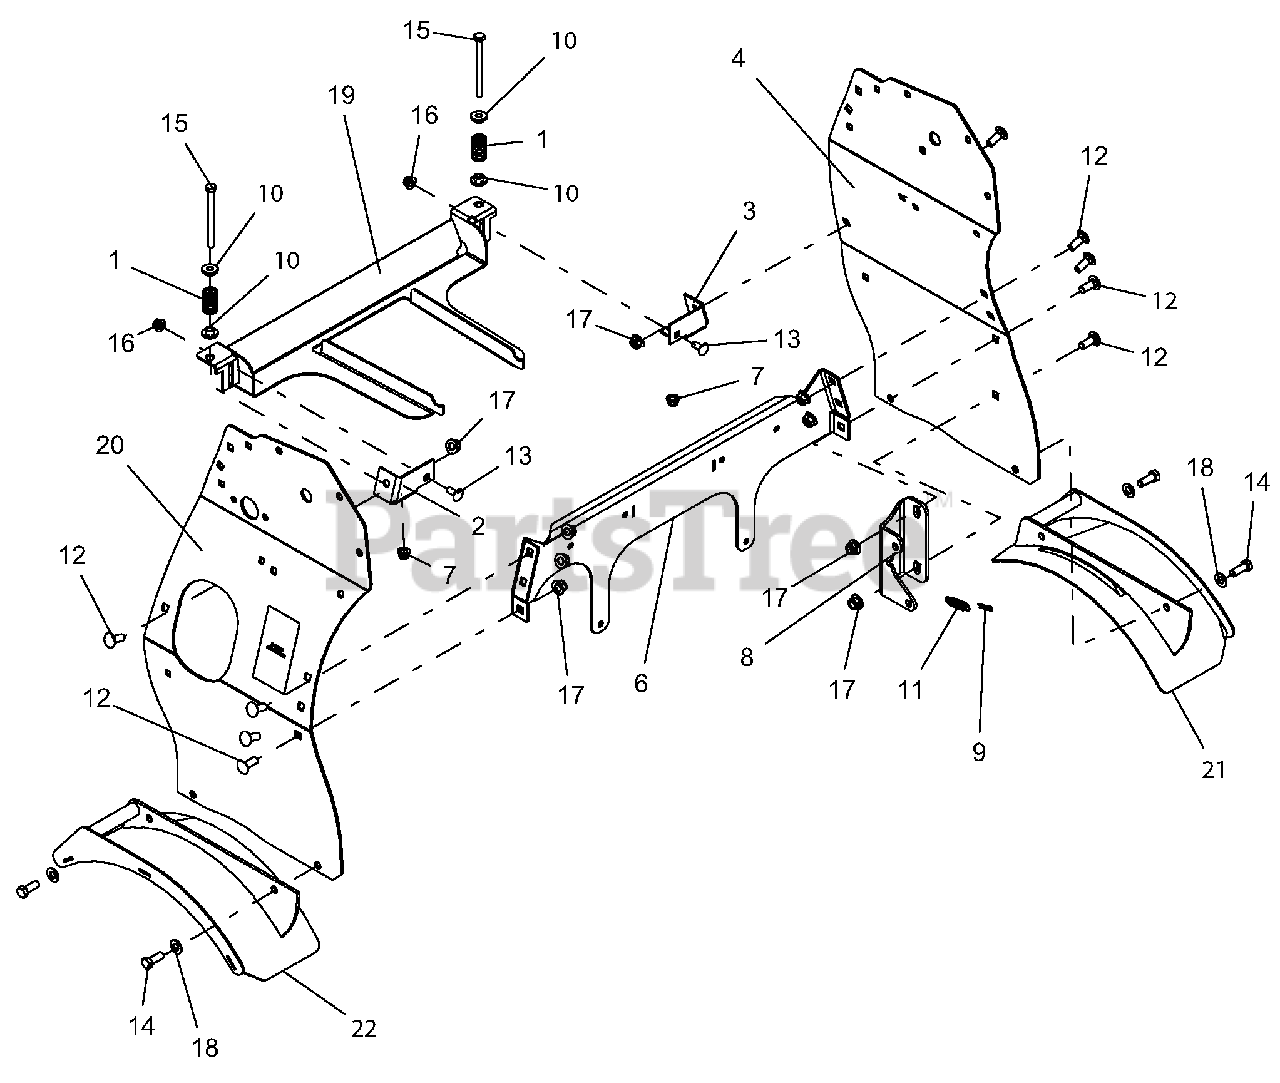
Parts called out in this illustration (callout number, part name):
1	SPRG, COMPRESSION
2	WLDMT, TANK HOLDDOWN-RH
3	WLDMT, TANK HOLDDOWN-LH
4	SIDE, LH PROSTANCE TOWER
6	BRKT, CONTROL TOWER STIFFENER
7	NUT-LK-NYL-FLG .31-18 YWZC
8	BRKT, TOWER SUPPORT
9	PIN-HAIR, ENDRIES #25 YWZC
10	BSHG, FLG .32X.500.344X.880
11	SPRG, EXTENSION
12	BLT-RDHDSQNK .38-16X1.00 G5 YWZC
13	BLT-RDHDSQNK .31-18X.75 G5 YWZC
14	BLT-HEX .38-16X1.00 GR5 YWZC
15	BLT-HEX .31-18X3.75 GR5 YWZC
16	NUT-LK-NYL-FLG .31-18 YWZC
17	NUT-LK-NYL-FLG .38-16 YWZC
18	WSHR-FL-STL.406X.812X.065 YWZ
19	HOLDDOWN, FUEL TANK
20	KIT, SERVICE RH TOWER
21	BRKT, LH FENDER
22	BRKT, RH FENDER
